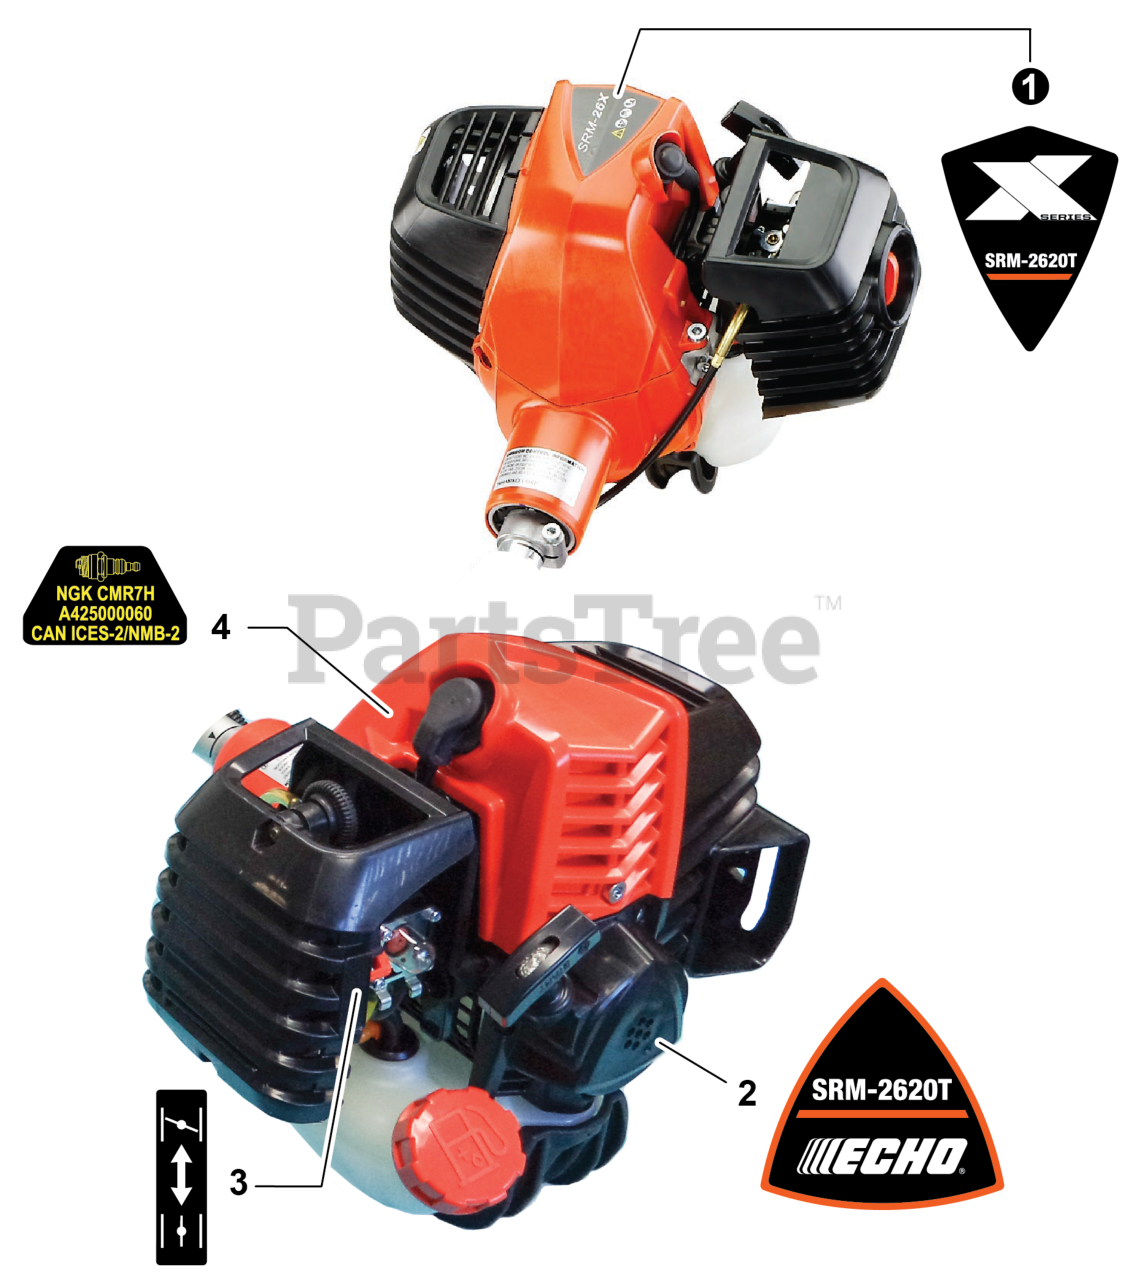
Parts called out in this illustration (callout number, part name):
1	LABEL - MODEL SRM-2620T
2	LABEL - STARTER - SRM-2620T
3	LABEL - CHOKE
4	LABEL - SPARK PLUG - CMR7H
